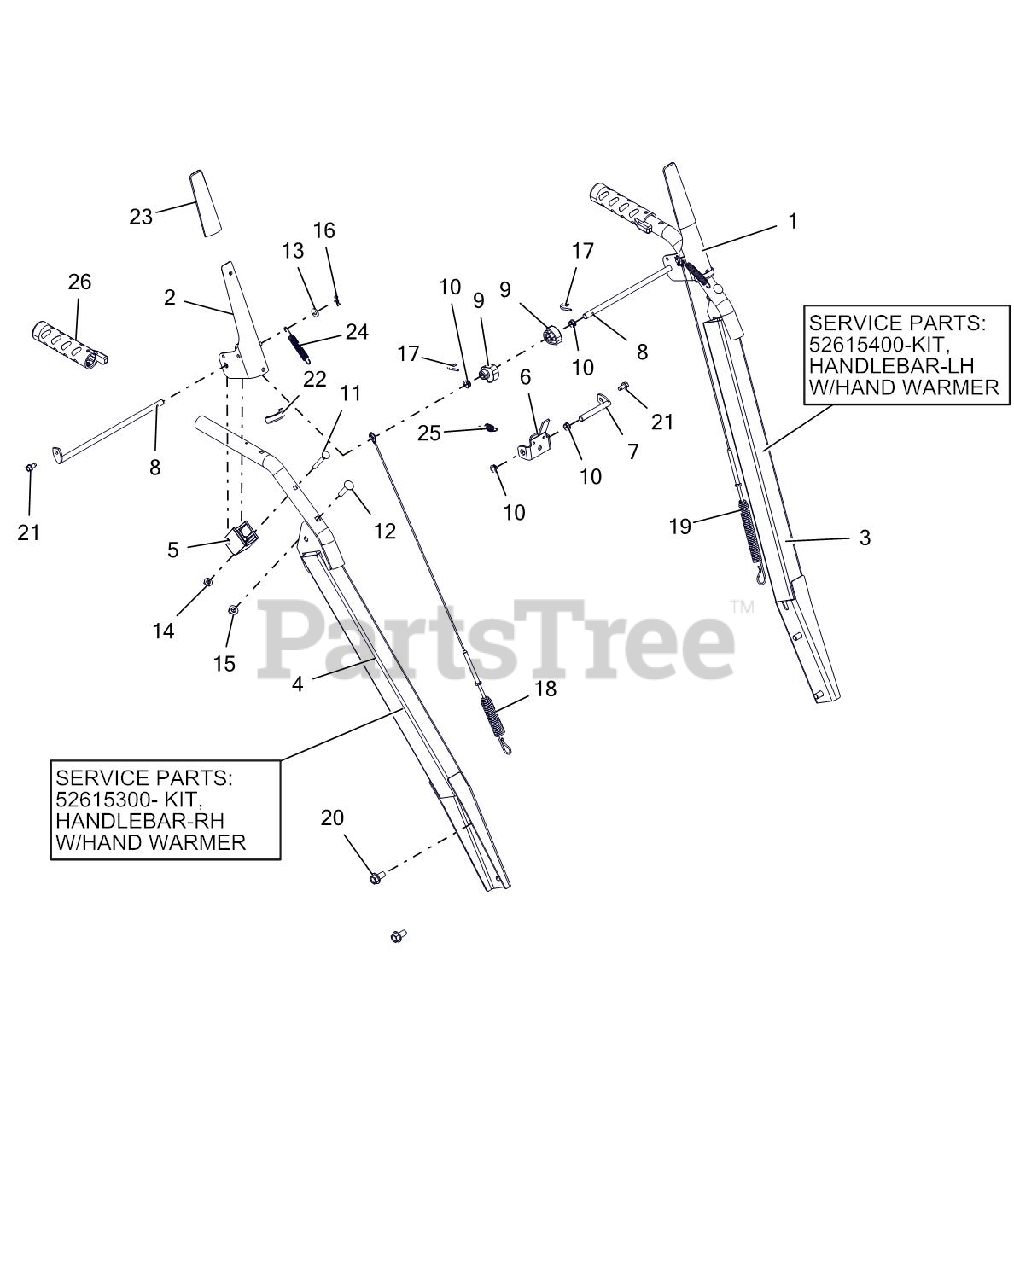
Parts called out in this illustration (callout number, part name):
1	LEVER, CLUTCH-LH
2	LEVER, CLUTCH-RH
3	HANDLEBAR, HEAVYDUTY-PRO LH
3	KIT, HANDLEBAR-LH W/WARM GRIP
4	HANDLEBAR, HEAVYDUTY-PRO-RH
4	KIT, HANDLEBAR-RH W/WARM GRIP
5	BLOCK, CLUTCH PADDLE
6	BRACKET, INTERLOCK ARM
7	ROD, PIVOT - INTERLOCK
8	ROD, PADDLE MOUNT - PRO
9	CAM, INTERLOCK
10	BUSHING, POLYLINER-.38 SNAPIN
11	BLT-RDHDXLSQNK .25-20X2.0 G5YZ
12	@BLT-RDHDSQNK .31-18X1.50 G5YZ
13	@WSHR-FL-STL.281X.62X.065 YWZC
14	@NUT-LK-CTR-FLG .25-20 YWZC
15	@NUT-LK-TOP-FLG .31-18 YWZC
16	PIN-HAIR INT .06X.18X.77
17	PIN, SPRING CLIP
18	CABLE, AUGER (DELUXE & PRO)
19	CABLE, UPPER TRACTION
20	BLT-SERHFWH .38-16X.75 YWZC
21	SCR-TAP .25-20X.50 HWH TR YWZ
22	EDGING, CLUTCH PADDLE - 2.00"
23	SLEEVE, CLUTCH PADDLE-GRAY
24	SPRING, EXTENSION
25	SPRING-EXT .047X.438X1.45
26	KIT, HANDWARMER - W/GLUE
